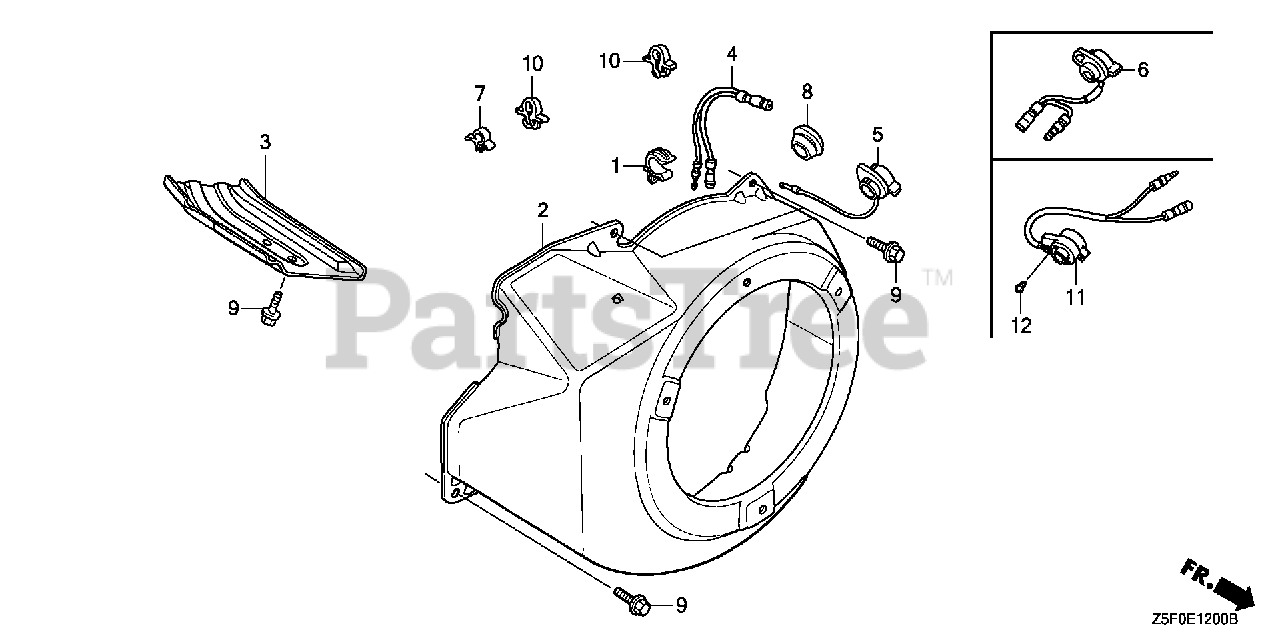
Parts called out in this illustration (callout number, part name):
1	CLIP, TUBE
2	COVER, FAN *NH1* (BLACK)
2	COVER, FAN *NH246* (LOOSY GRAY)
2	COVER, FAN *R280* (POWER RED)
6	SWITCH ASSY., ENGINE STOP
9	BOLT, FLANGE (6X12) (CT200)
